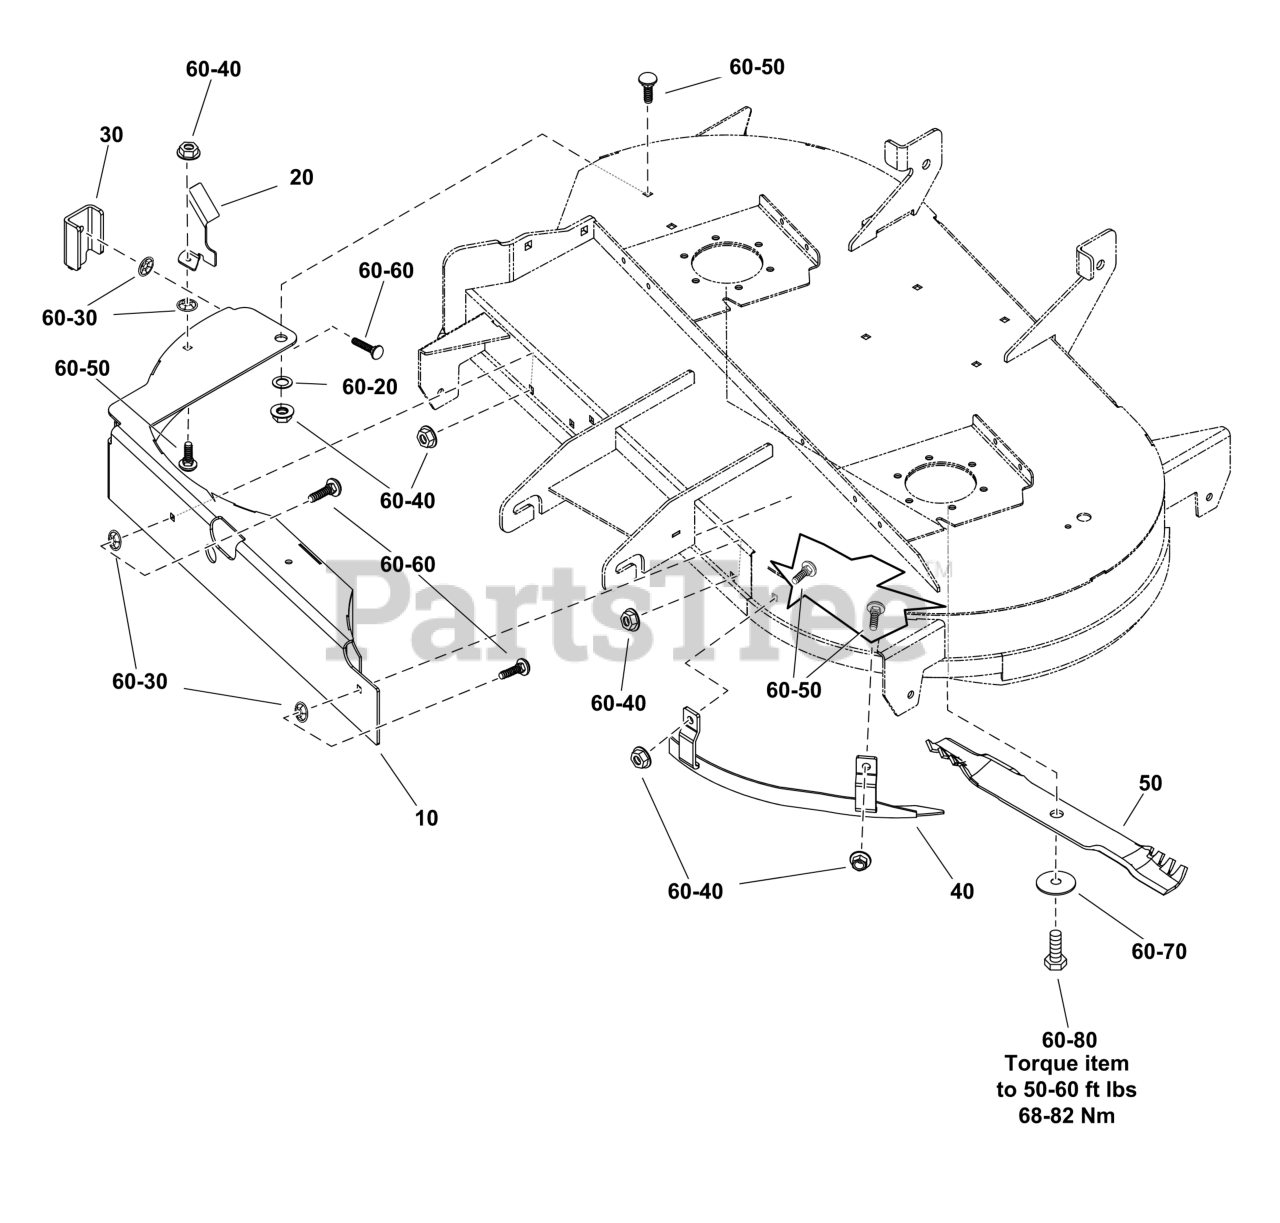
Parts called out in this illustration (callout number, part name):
10	BAFFLE, Mulching
20	SUPPORT, Deflector
30	LATCH, Discharge
40	BAFFLE, Front
50	BLADE-MULCHING
60-20	WASHER, 5/16
60-30	RETAINER, GR5, 5/16
60-50	BOLT, 5/16-18X.875
60-60	BOLT
60-70	WASHER, SPRING 0.475I
60-80	CAPSCREW-HEX HD 7/16-
